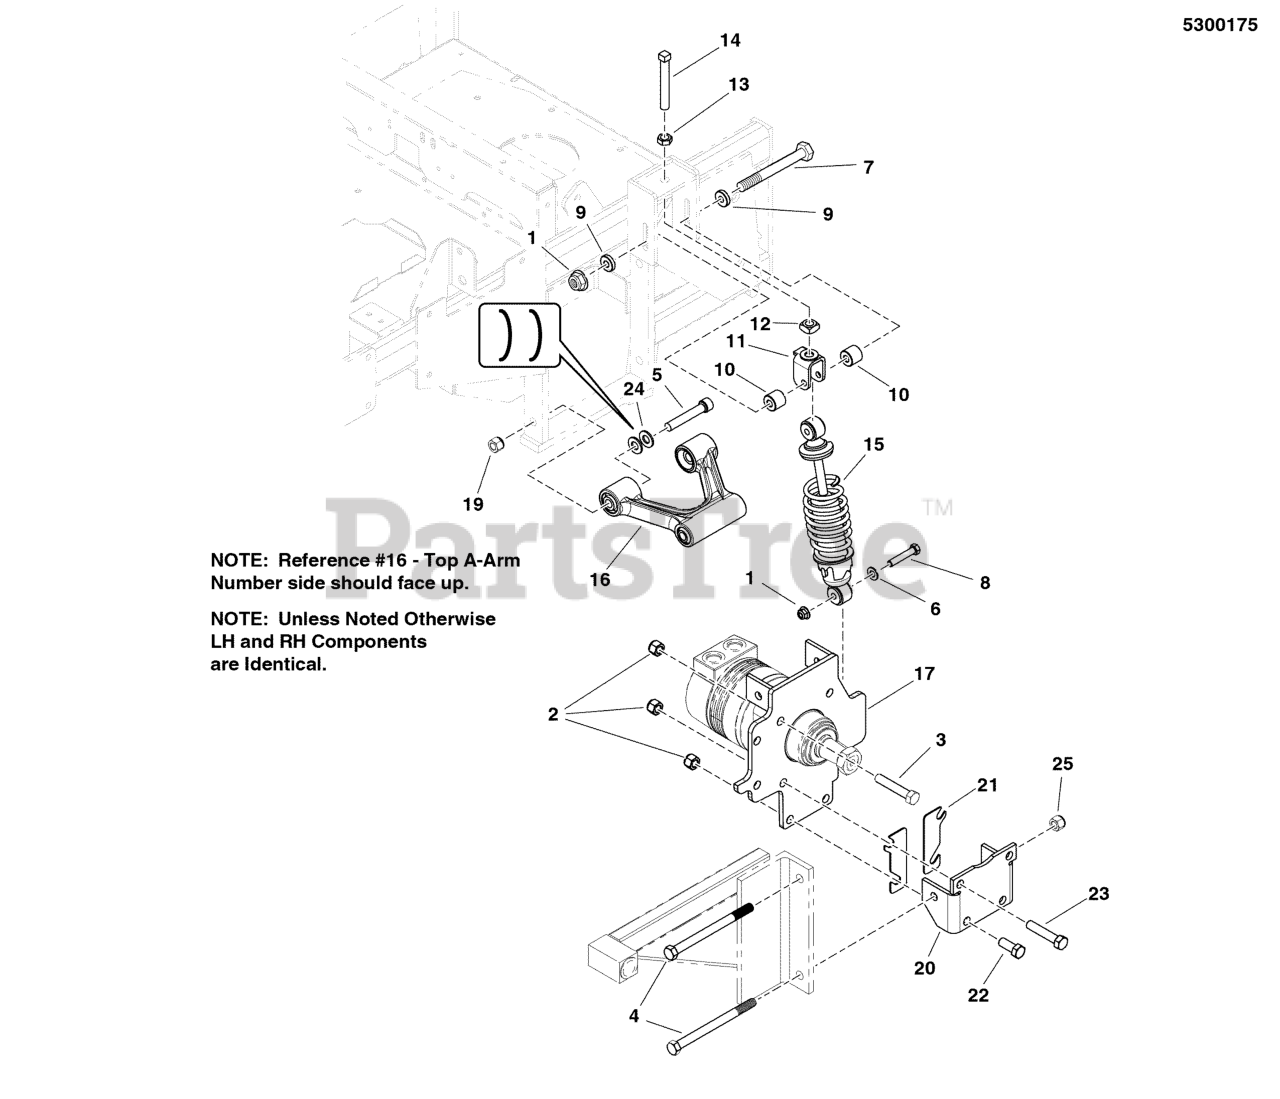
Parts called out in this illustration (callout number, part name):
1	NUT, 3/8 - 16 HEX NYLOCK FLANGE
2	NUT, Hex, Nylon Lock, 1/2-20
3	BOLT, 1/2-13 X 2-1/2" GD5 CZ
4	BOLT, 1/2-13 X 6-1/2" GD8 YZ
5	BOLT, 1/2-13 X 3-1/4" ALLEN HEAD
6	WASHER, 3/8 SAE
7	BOLT, 3/8-16 X 5" GD5
8	BOLT, 3/8-16 X 2, GD5, CZ
9	SPACER, .39 X 1.00 X .25
10	SPACER, .39 X 1.00 X .88, CZ
11	WELD, JACK BOLT PLATFORM - RED
12	NUT, 1/2-13 Square
13	NUT, Hex, Jam, 1/2-13
14	SET SCREW, Square Head, 1/2-13 x 3
15	SHOCK/SPRING ASSEMBLY, IS3000
16	ASSM, A-ARM WITH BEARINGS
17	WELD, MOTOR MOUNT, LH - 3100 - BLK
19	NUT, 1/2-13 HEX NYLOCK FLANGE GR8, YZ
21	SHIM, CAMBER - PLATED
22	BOLT, 1/2-20 X 1-3/4" GD8 CZ
23	BOLT, 1/2-13 X 3" GD5 CZ
24	BELLEVILLE WASHER, 1.259 X .512 X .138 YZ
25	NUT, Hex Flange, Nylock, 1/2-13
